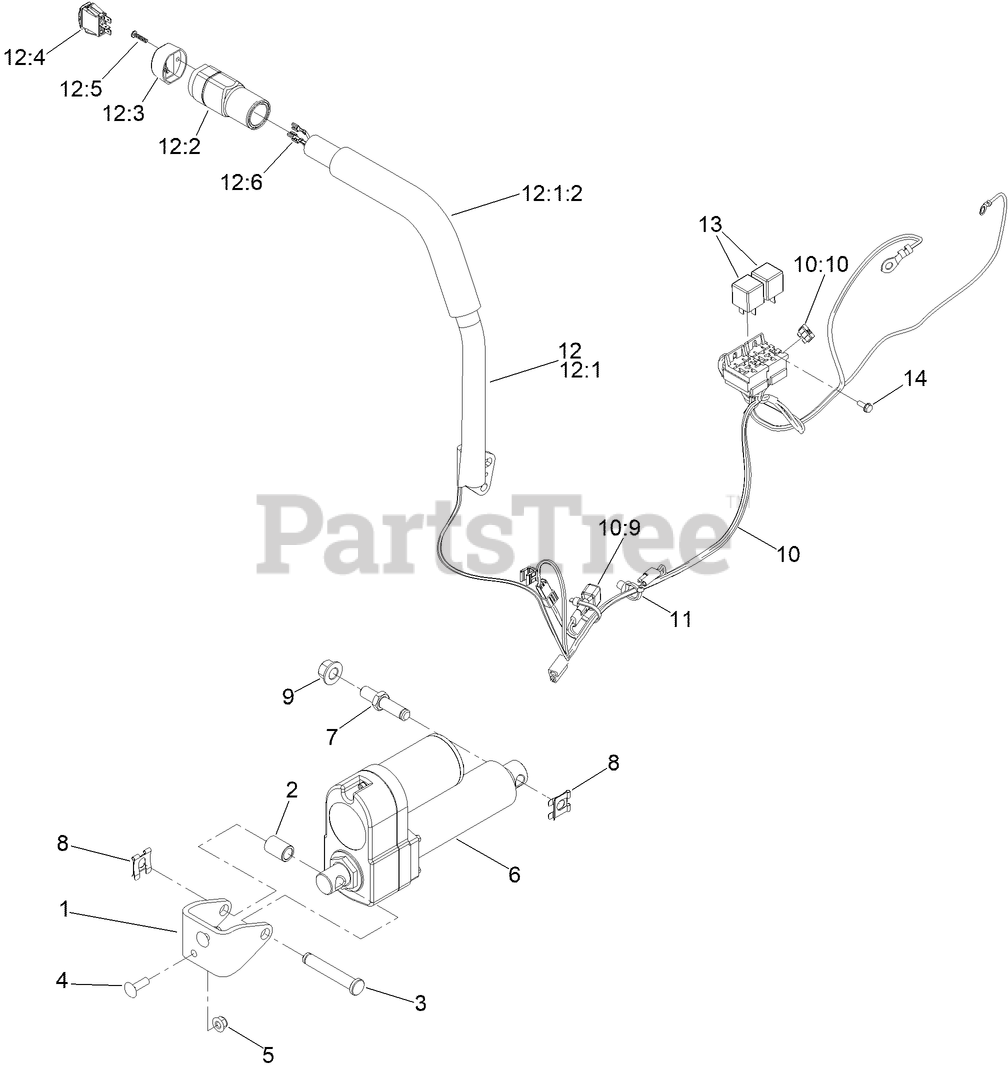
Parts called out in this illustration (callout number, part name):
1	CYL MOUNT PLATE
2	SPACER-ALUMINUM
3	PIN-CLEVIS
4	SCREW-CARR
5	NUT-HF, NI
6	ACTUATOR-LINEAR
7	PIN-PIVOT, ACTUATOR
8	CLIP-PIN
9	NUT-LOCK
10	HARNESS-WIRE, DECK LIFT
10:10	FUSE-BLADE, 20 AMP
11	CLIP-TIE
12	HANDLE ASM-LH
12:1	HANDLE ASM-LH
12:1:2	GRIP-CONTROL, LEVER
12:2	CASE ASM
12:3	CAP-SWITCH
12:4	Air Cleaner Element
12:5	SCREW-PPH
12:6	HARNESS-WIRE, HANDLE
14	SCREW-TAPTITE
